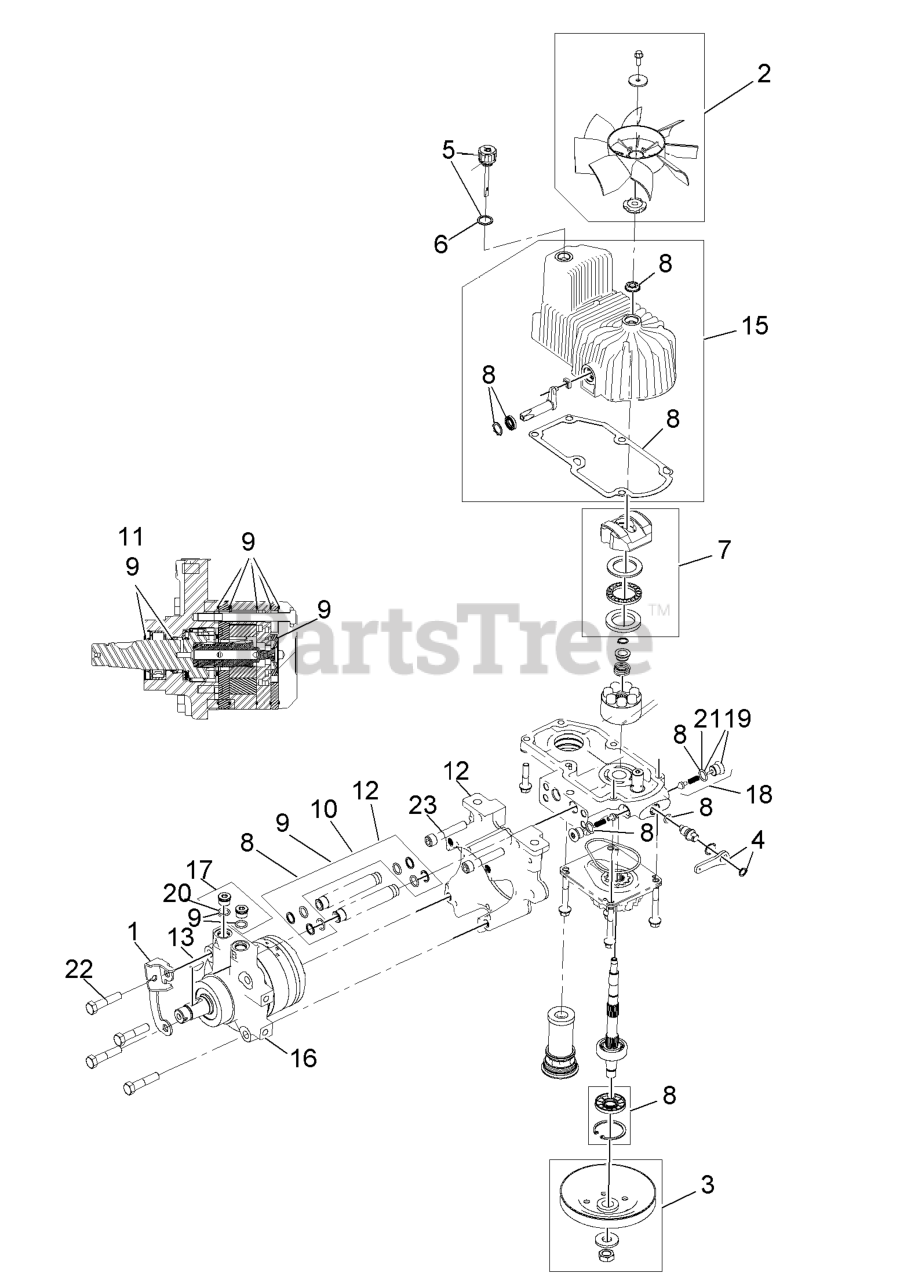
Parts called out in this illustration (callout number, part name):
1	BRACKET-ANCHOR, CABLE
2	FAN KIT
3	PULLEY KIT
4	HANDLE-BYPASS VALVE, HYDRO
5	DIPSTICK-HYDRO W/GASKET
6	GASKET-DIPSTICK, HYDRO
7	SWASH BLOCK KIT
8	PUMP SEAL KIT
9	MOTOR SEAL KIT
10	TUBE SEAL KIT
11	OUTPUT SHAFT SEAL KIT
12	NOSE CUP-UHT
13	KEY-WOODRUFF
15	HOUSING-HYDRO, LH
16	MOTOR-HYDRAULIC LH 240CC
17	MAGNETIC PLUGS SERVICE KIT
18	CHECK VALVE ASM
19	PLUG-CHECK (W/O-RING)
21	O-RING-CHECK VALVE
22	SCREW HH
23	SCREW-HSH
